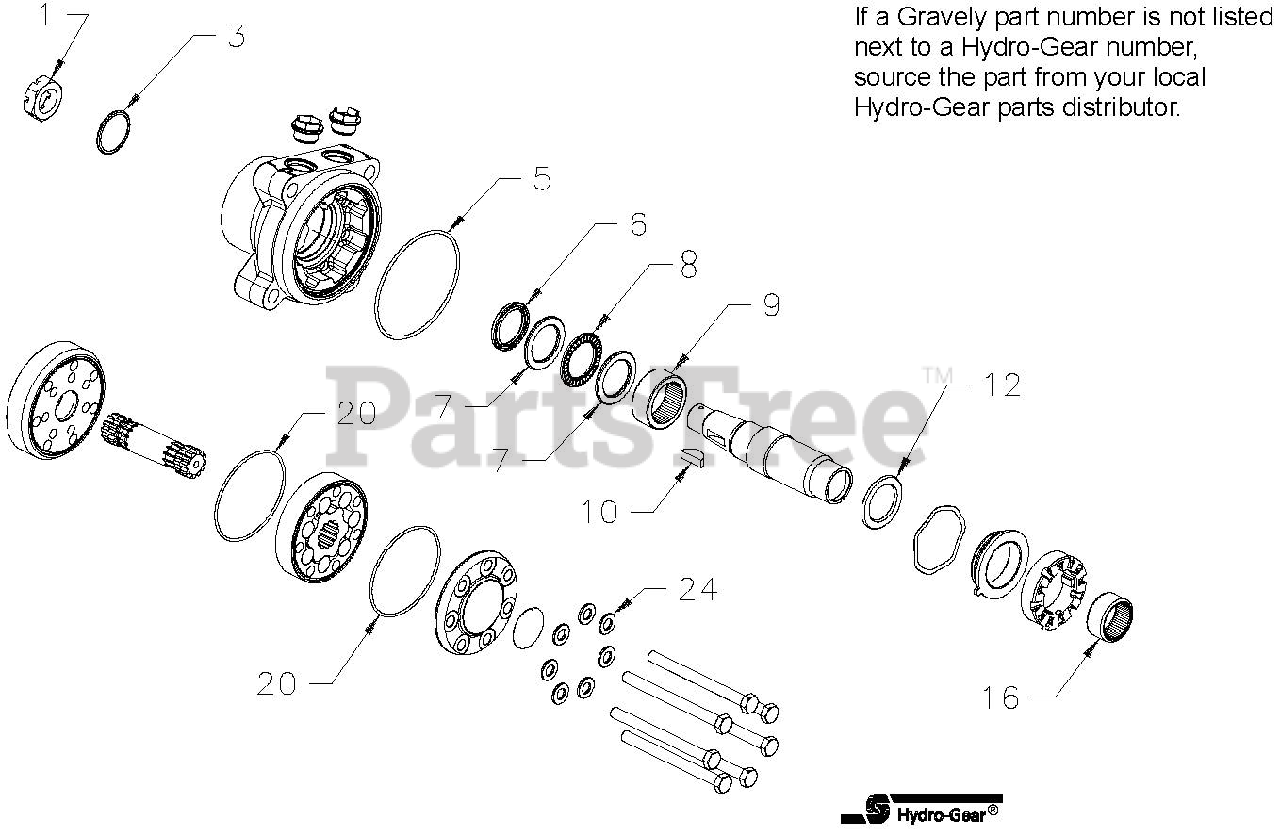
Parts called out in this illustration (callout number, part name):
1	Nut, Castle 1-20 Slotted Hex
10	Key, Woodruff 5/16 x 1
NS	Seal Kit
NS	Kit, Axial Needle Bearing HGM E-Series
